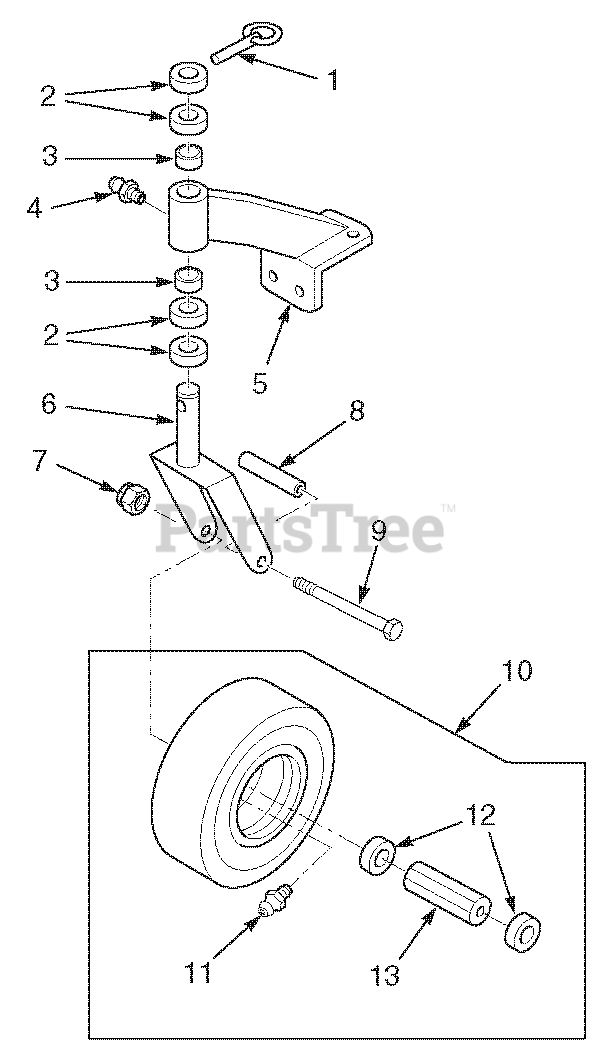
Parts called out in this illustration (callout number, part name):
1	Quick Pin
2	Spacer, Spacer Yoke, 1/2" Long
3	Bronze Bearing
4	Greasing Fitting
5	Support Assembly
6	Caster Yoke
7	Nut, Elastic Stop 1/2-13
8	Sleeve, Caster Wheel Bearing
9	Bolt, Hex Head 1/2-13 x 5-1/2"
10	Flat-Free Tire Assy.
11	Grease Fitting, 45 Degree 1/4-28
12	Retainer, Caster Wheel Bearing
13	Roller Bearing, Caster Wheel
